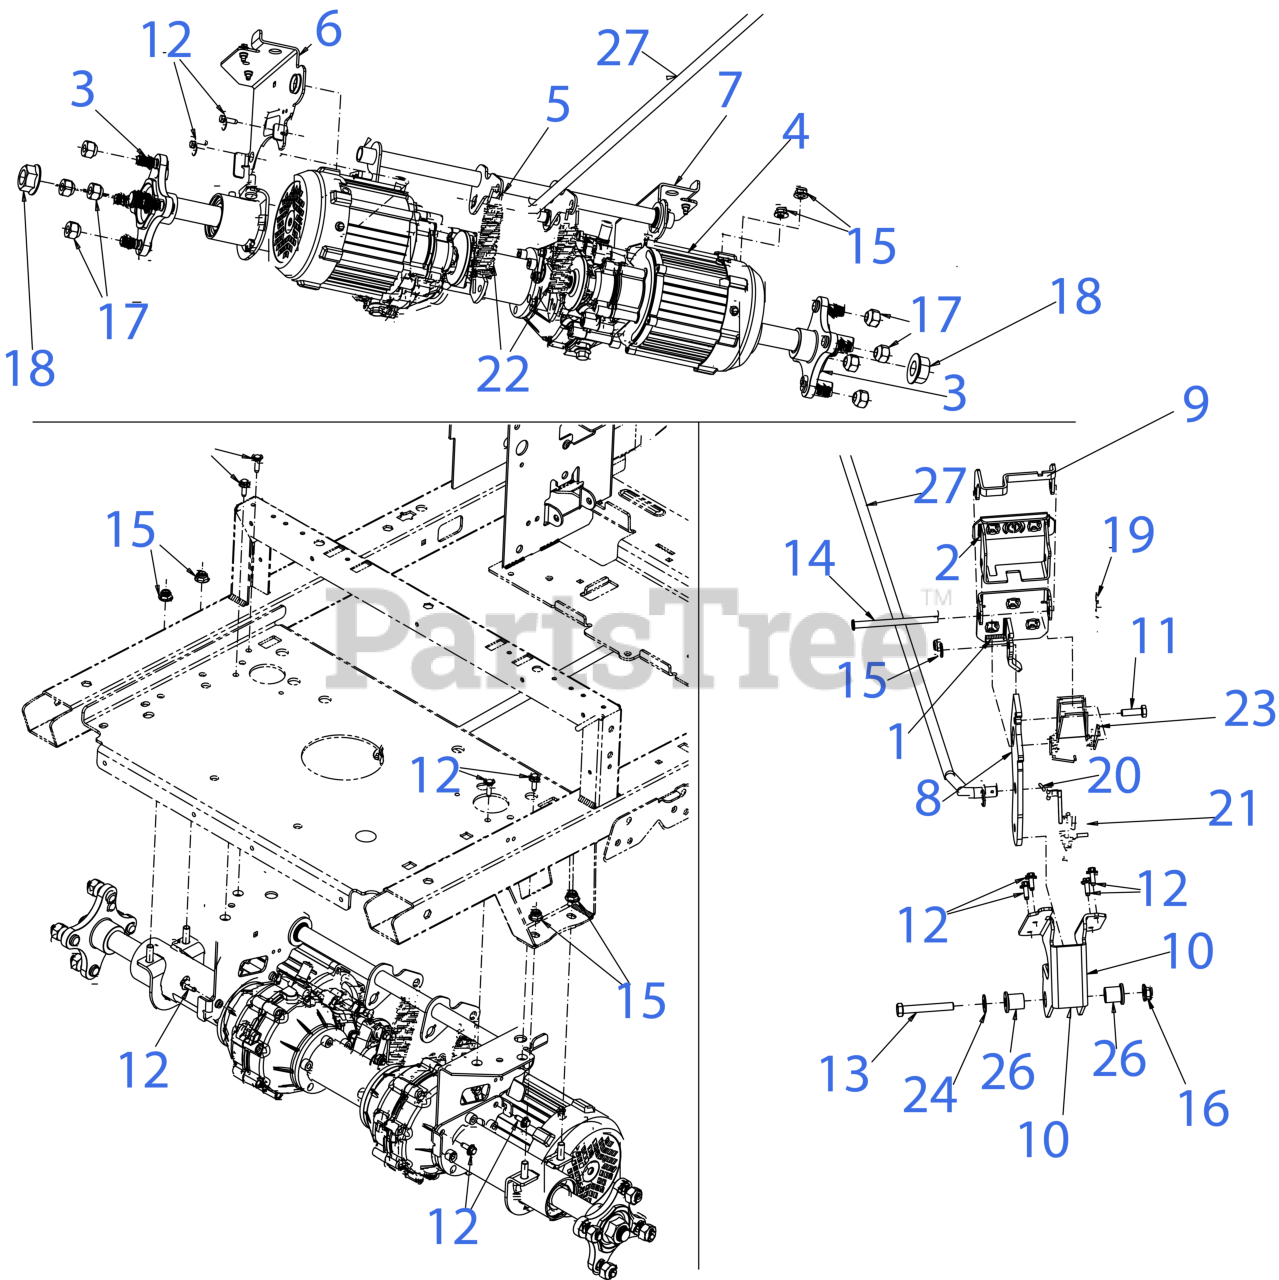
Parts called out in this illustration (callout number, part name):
1	PED ASM:BRAKE:PRK:LWR
2	PED ASM:BRAKE:PRK:UPPR
3	WHEEL HUB ASSEMBLY
3	STUD 7/16-14 x 1.6
4	TRANS:ASM:ELEC ZT
5	ELECTRIC BRAKE SHAFT
6	TRANSMISSION SUPPORT (RH)
7	TRANSMISSION SUPPORT (LH)
8	PED:BRAKE:PARK:ARM
9	PED:BRAKE:STOP:LATCH
10	SUPT:PED:BRAKE
11	SCREW 5/16-18 x 1.0 GR5
12	SCREW M6-1 x .625
13	HEX SCREW-3/8-16X2.5 GR5
14	CLEVIS PIN 5/16 x 4.135
15	FLANGE LOCK NUT 5/16-18
17	LUG NUT 7/16-14
18	HEX FLANGE NUT 3/4
19	BOW TIE COTTER PIN 1/4-5/16
20	COTTER PIN
21	TORSION SPRING 1.391 ID x .56 LG
22	SPRING .925 DIA x 5.37
23	SPR:TORSN:DOUBLE
24	FLAT WASHER
26	FLANGE BEARING (.38x.75x.77)
27	BRAKE ROD
